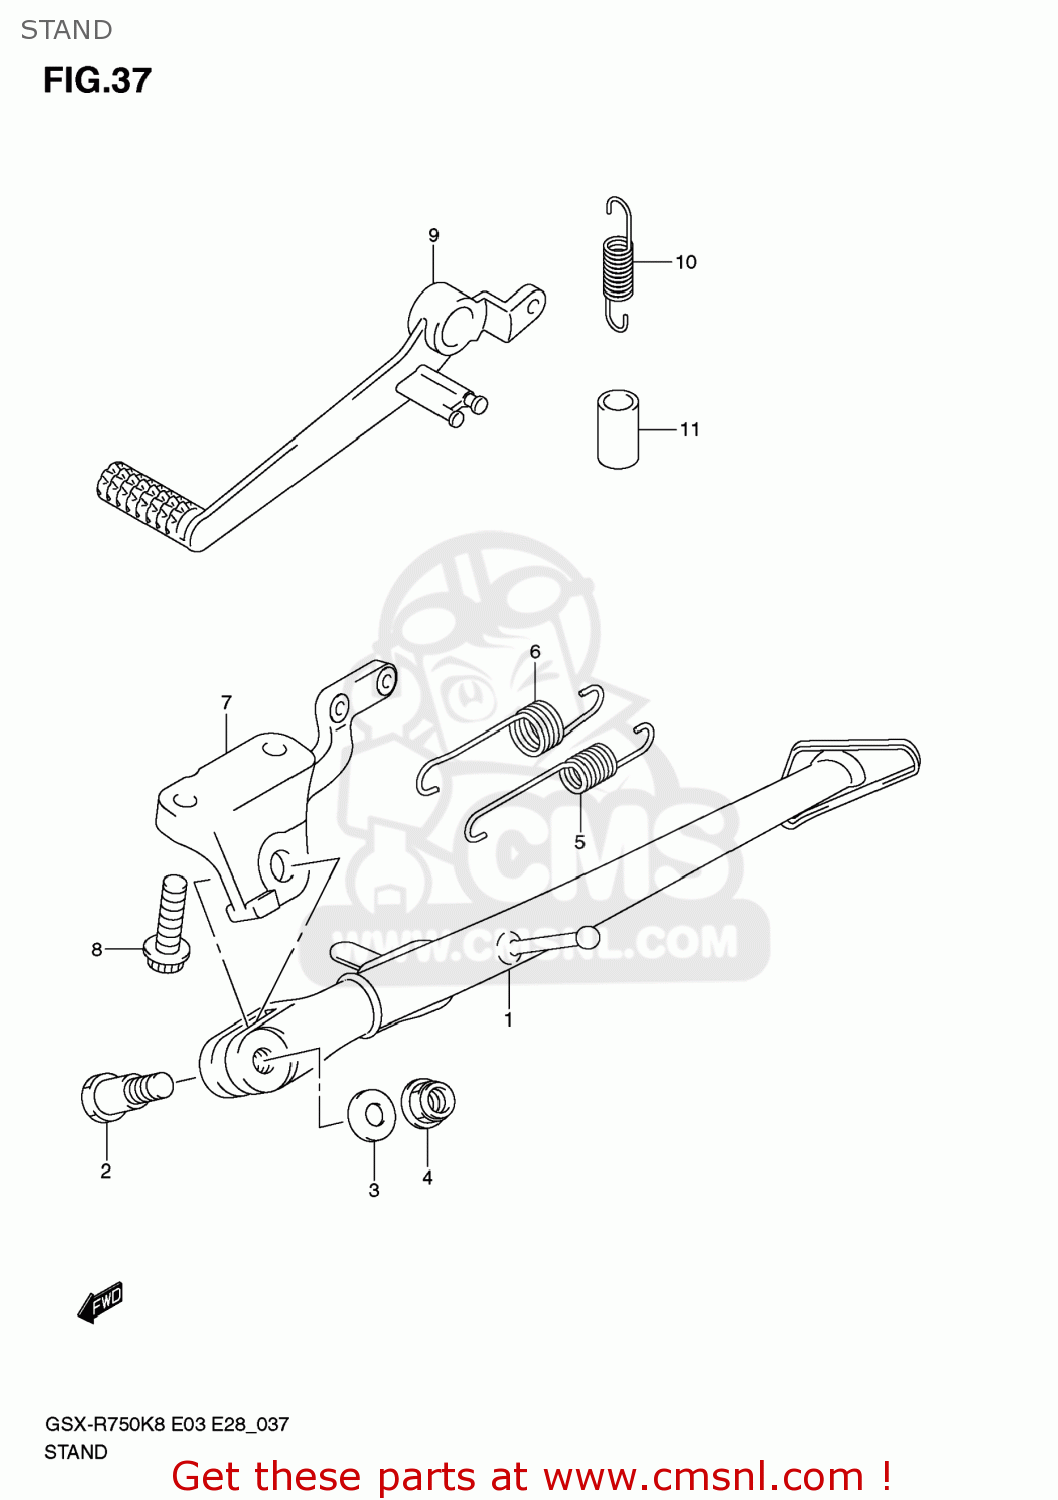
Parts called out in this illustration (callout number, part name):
1	STAND,PROP
2	BOLT(10X37.5)
3	SEAT,VALVE SPRING EXH OUTER
4	NUT
5	SPRING
6	SPRING
7	BRACKET,PROP STAND
8	BOLT(10X28)
9	PEDAL,BRAKE
10	SPRING
11	HOSE(11X15X600)
